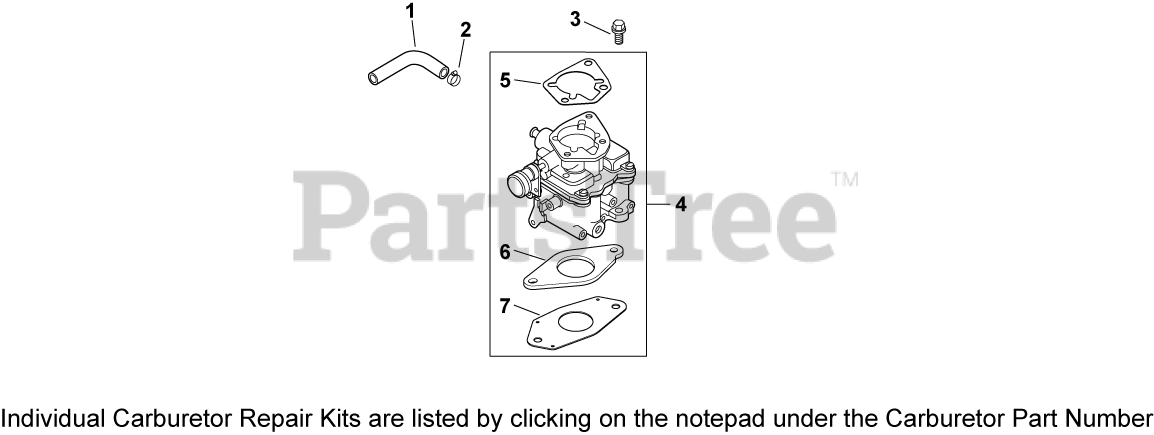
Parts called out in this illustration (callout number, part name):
1	LINE, FLEXIBLE FUEL 9.30"-USE 25 111 81-
2	CLAMP, HOSE (KM)-USE 25 237 31-S
3	SCREW, FLG M6X1.0X30
4	KIT, CARBURETOR W/GASKET KSF
5	GASKET, AIR CLEANER BASE
6	GASKET, CARBURETOR
7	GASKET, CARBURETOR
